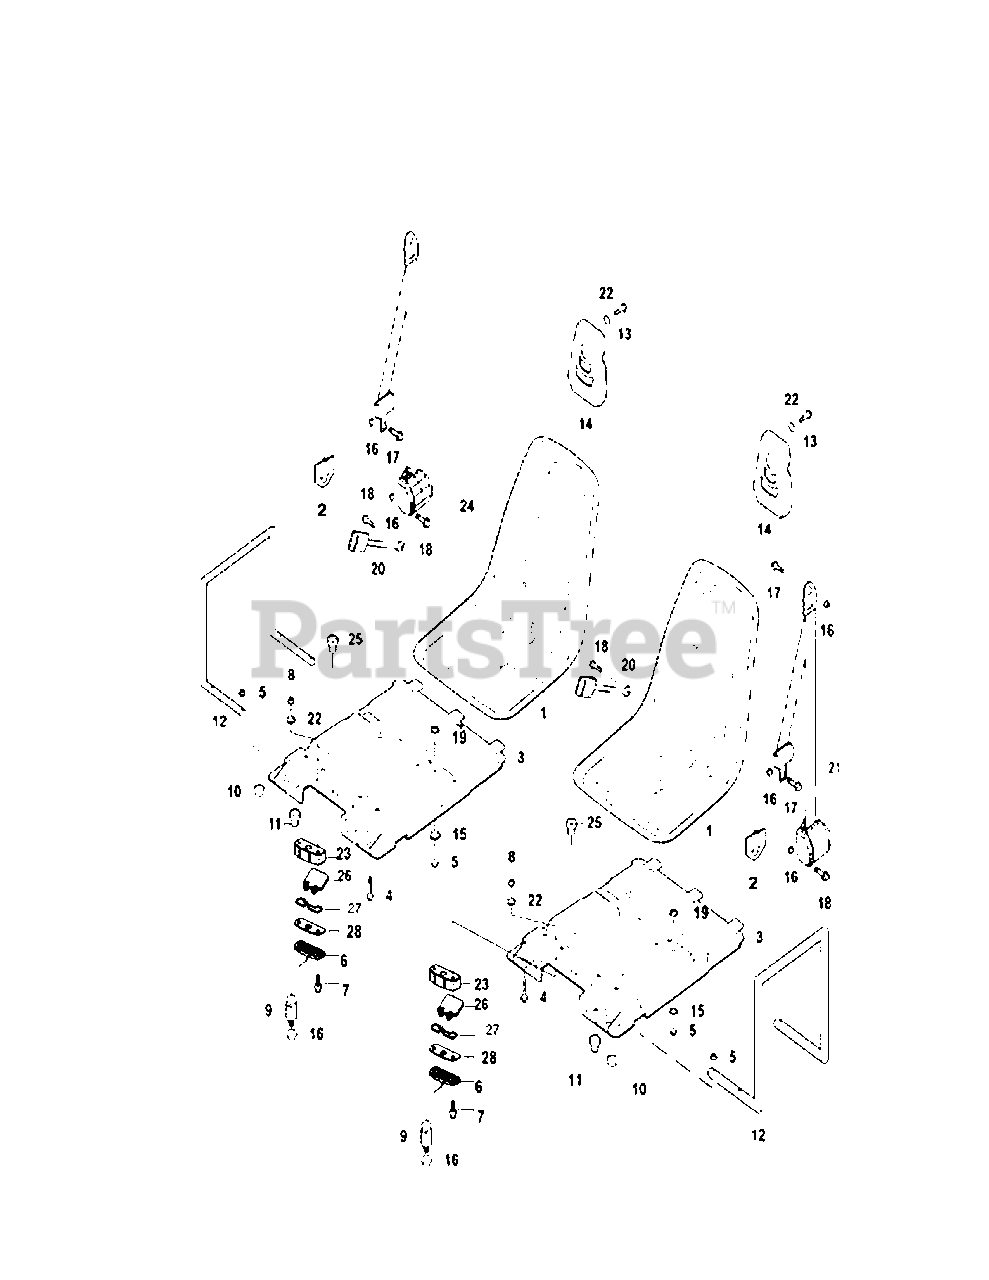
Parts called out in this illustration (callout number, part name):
1	Seat Assy
2	Safty Belt Placing Plate
3	Seat Mounting Board
4	Hexagon Flange Bolt M8×30
5	Hexagon Flange Nut M8
6	Seat Locker Cover
7	Hexagon flange bolt M6×40
8	Hexagon Flange Nut M6
9	Locker Bracket, Seat
10	Shock Absorber Cushion III
11	Shock Absorber Cushion VII
12	Side Armrest
13	Hexagon Flange Bolt M6×25
14	Head Rest
15	Cushion 8.5×28×1.5
16	Hexagon flange nut M10×1.25
17	Hexagon Flange Step Bolt M10×1.25×20-14×5
18	Hexagon flange bolt M10×1.25×20
19	Cushion 10.5×25×3
20	Safety Belt Buckle
21	Safety Belt Assy (L)
22	Washer6×18×1.6
23	Seat Locker Body
24	Safety Belt Assy
25	Collar Bushing 8×25×36×7
26	Seat Locker Lever
27	Seat Locker Spring
28	Seat Spring Pressure-plate
